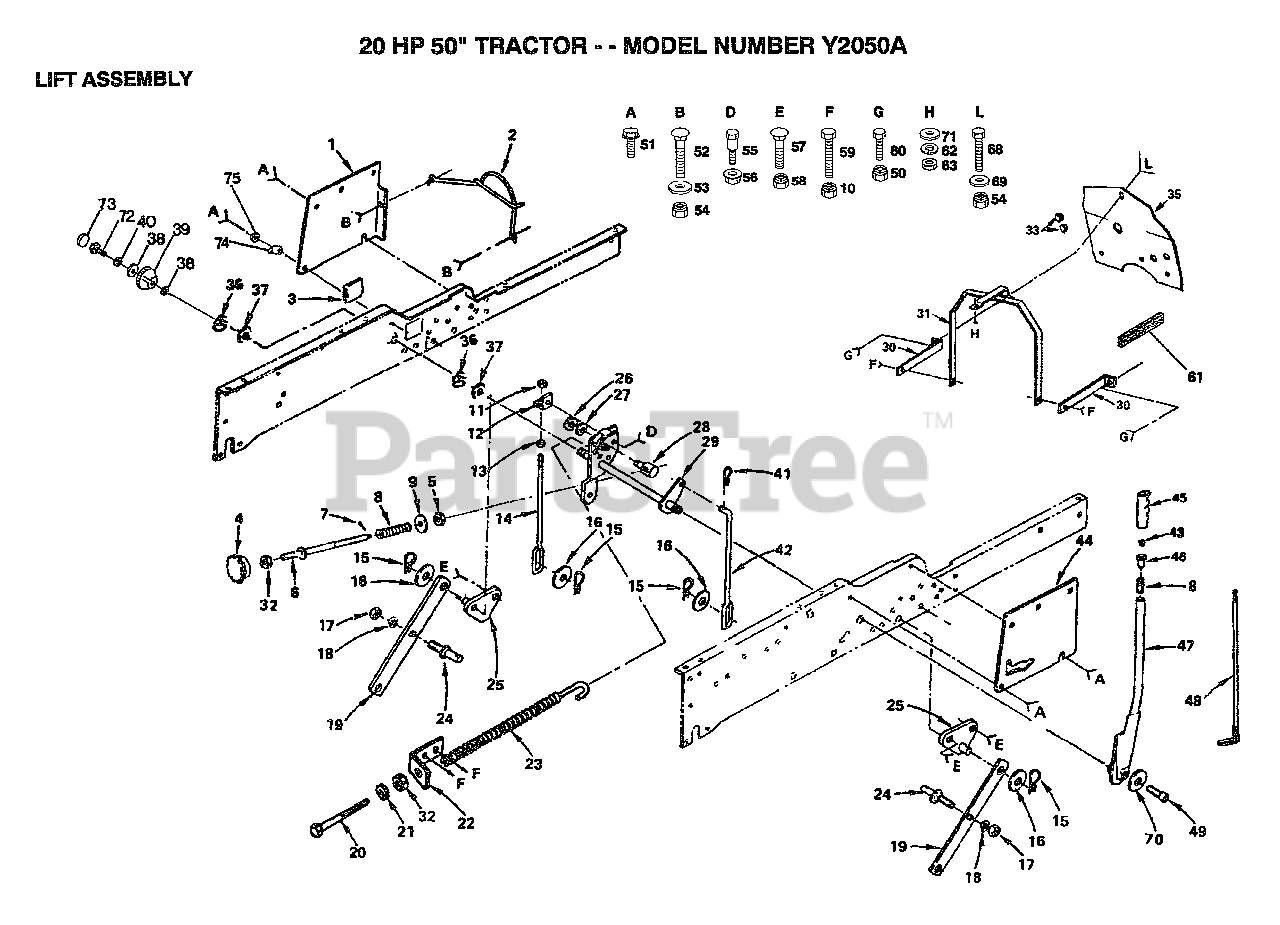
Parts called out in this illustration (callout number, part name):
2	"GUARD, BELT"
3	COVER ACCESS
5	NUT T
6	ROD ADJ. T
8	SPRING T
9	WASHER
11	NUT
12	BRACKET T
13	NUT.HEX.3/8-16UNC
14	LINK-LIFT MOW T
15	SPRING H
17	NUT
18	LOCKWASHER
19	SUSPENSION ARM GT
20	BOLT-ADJ SPRING T
21	WASHER
24	PIVOT STUD GT
25	SUSP BRACKET T
26	KLIP RING
27	WASHER
28	TRUNION LT
29	SHAFT ASS'Y LIFT
30	BRACKET T
32	NUT
35	"SHIELD HEAT, BASE"
36	E-RING
37	WASHER
38	WASHER
39	HEIGHT INDICATOR
40	LOCKWASHER
42	LIFT LINK RH T
45	GRIP
48	LEVER ROD LT
49	"BOLT,HEX"
51	SCREW LT
52	BOLT
53	WASHER
55	SHOULDER BOLT T
56	NUT T
57	BOLT
58	LOCKNUT
59	BOLT
60	BOLT
61	FOAM STRIP T
68	BOLT
69	WASHER M
70	LOCKWASHER
71	WASHER PM
73	"PLUG,HOLE"
75	WASHER T
